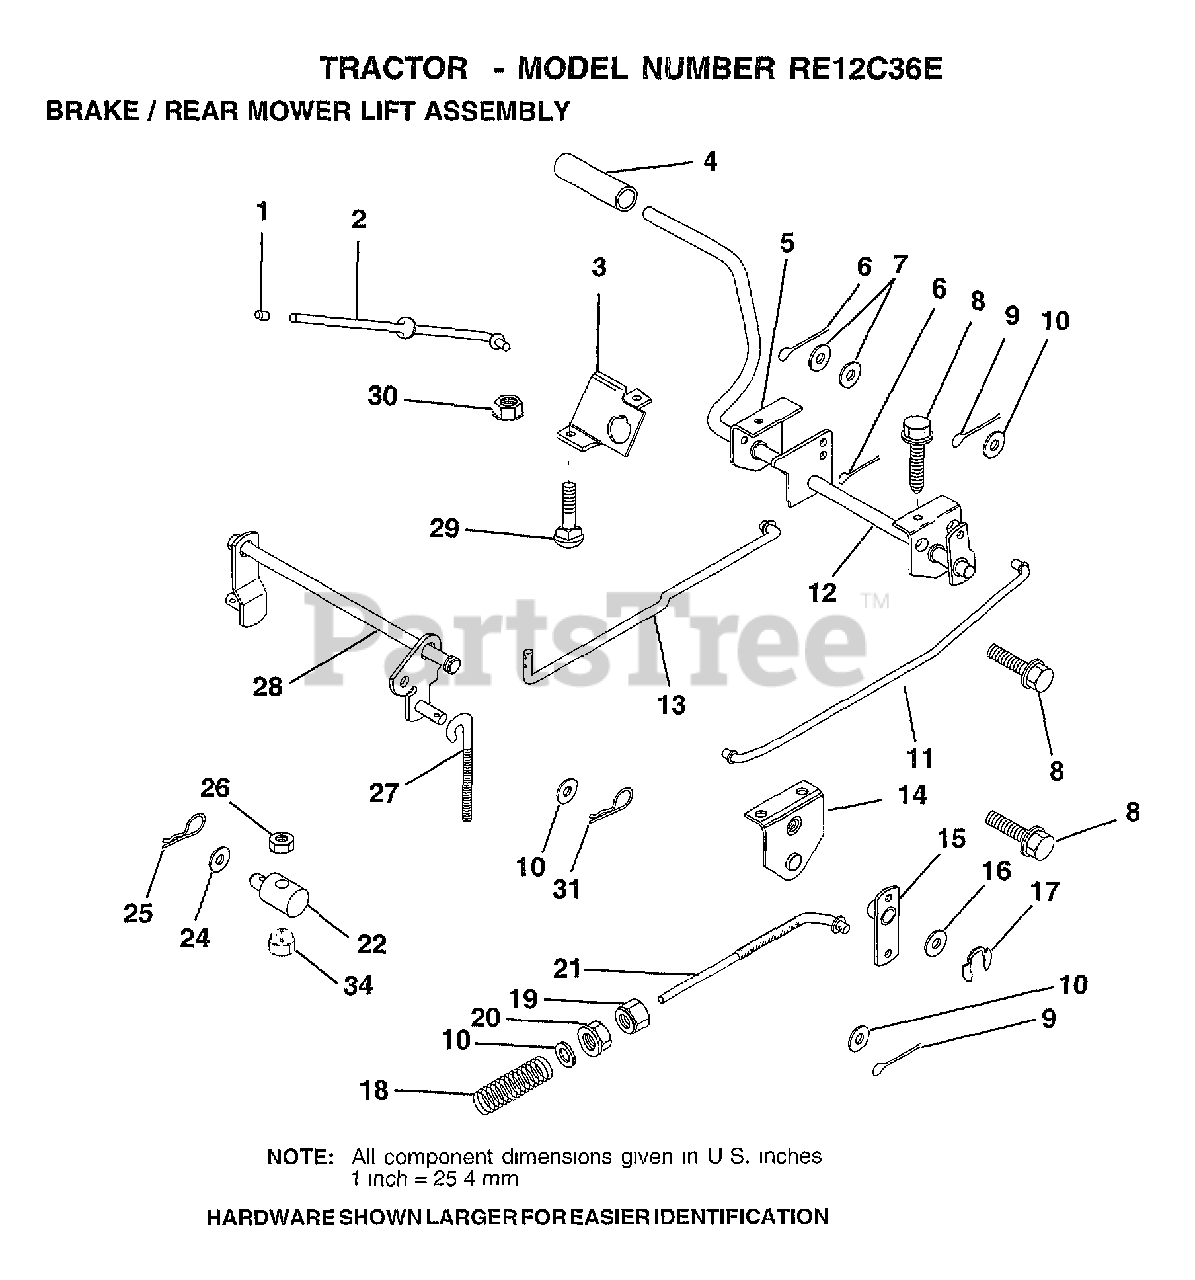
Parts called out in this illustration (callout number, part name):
1	PLUNGER CAP T
2	"ROD,PARK BRAKE"
3	"BRKT,PARK BRAKE"
4	FOOT PEDAL COVER
5	"BRKT,CLU PEDAL LH"
7	WASHER
8	SCREW LT
9	COTTER PIN
10	WASHER
11	"ROD,FRT BRAKE"
12	PEDAL ASM CL/BK36
13	"ROD,CLUTCH"
14	"BRKT,LIFT SHAFT"
15	PVT BRAKE ARM ASM
16	WASHER T
17	KLIP RING
18	SPRING ROD BRAKE
19	NUT
20	NUT
22	TRUNNION.LIFT.
24	WASHER
25	SPRING.RETAINER
26	LOCKNUT
27	"LINK, MOWER REAR"
28	LIFT ASM MOW REAR
31	RETAINER.SPRING
